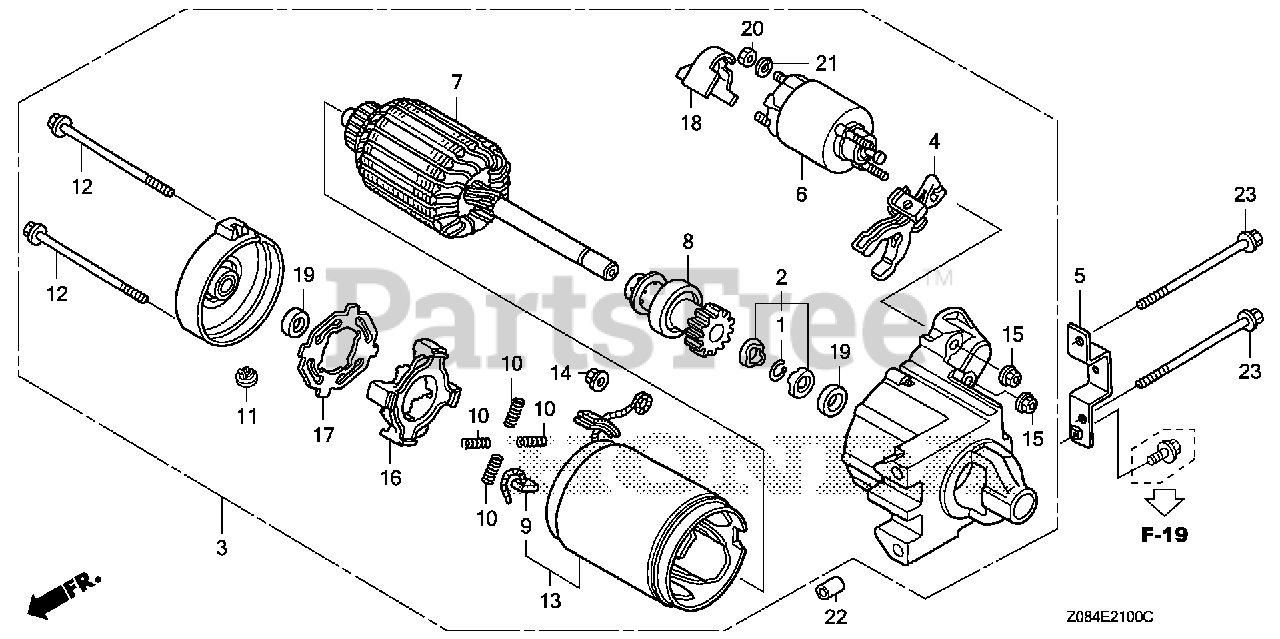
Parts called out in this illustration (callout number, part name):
1	RING, SNAP (DENSO)
2	COLLAR SET, CLUTCH STOP
3	STARTER MOTOR ASSY.
4	LEVER, PINION DRIVE
5	BRACKET, WIRE HARNESS CLIP (A)
6	SWITCH ASSY., MAGNET
8	CLUTCH, OVERRUNNING
10	SPRING, BRUSH
12	BOLT, THROUGH
14	NUT, HEX. (8MM)
16	HOLDER, BRUSH
17	INSULATOR, BRUSH HOLDER
18	COVER, TERMINAL
20	NUT, HEX. (8MM)
21	WASHER, SPRING (8MM)
22	PIN, DOWEL (10X12)
23	BOLT, FLANGE (8X110)
